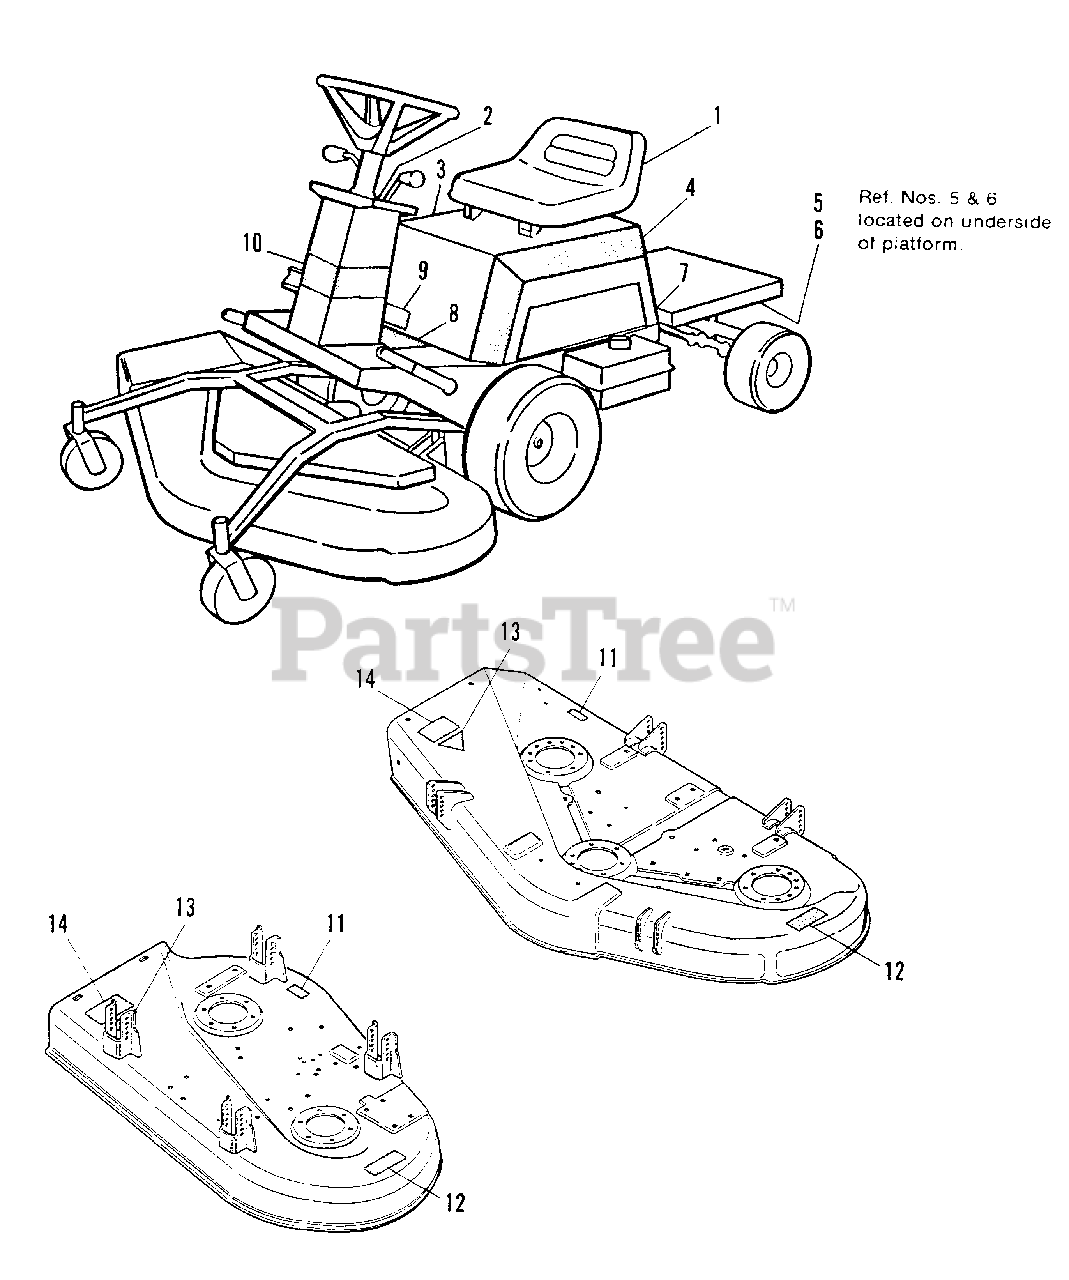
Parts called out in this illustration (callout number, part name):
1	DECAL, Simplicity
2	DECAL, Instrument Panel
3	DECAL, Side, R.H.
4	DECAL, Side, L.H.
5	DECAL, Drive Belts
6	DECAL, Stability
7	I.D. PLATE
8	DECAL, Caution & Controls
9	DECAL, Model No. 12 HP Hydro
10	DECAL, Steering Column
11	I.D. PLATE
12	DECAL, Danger
13	DECAL, OPEI
14	DECAL, Danger
